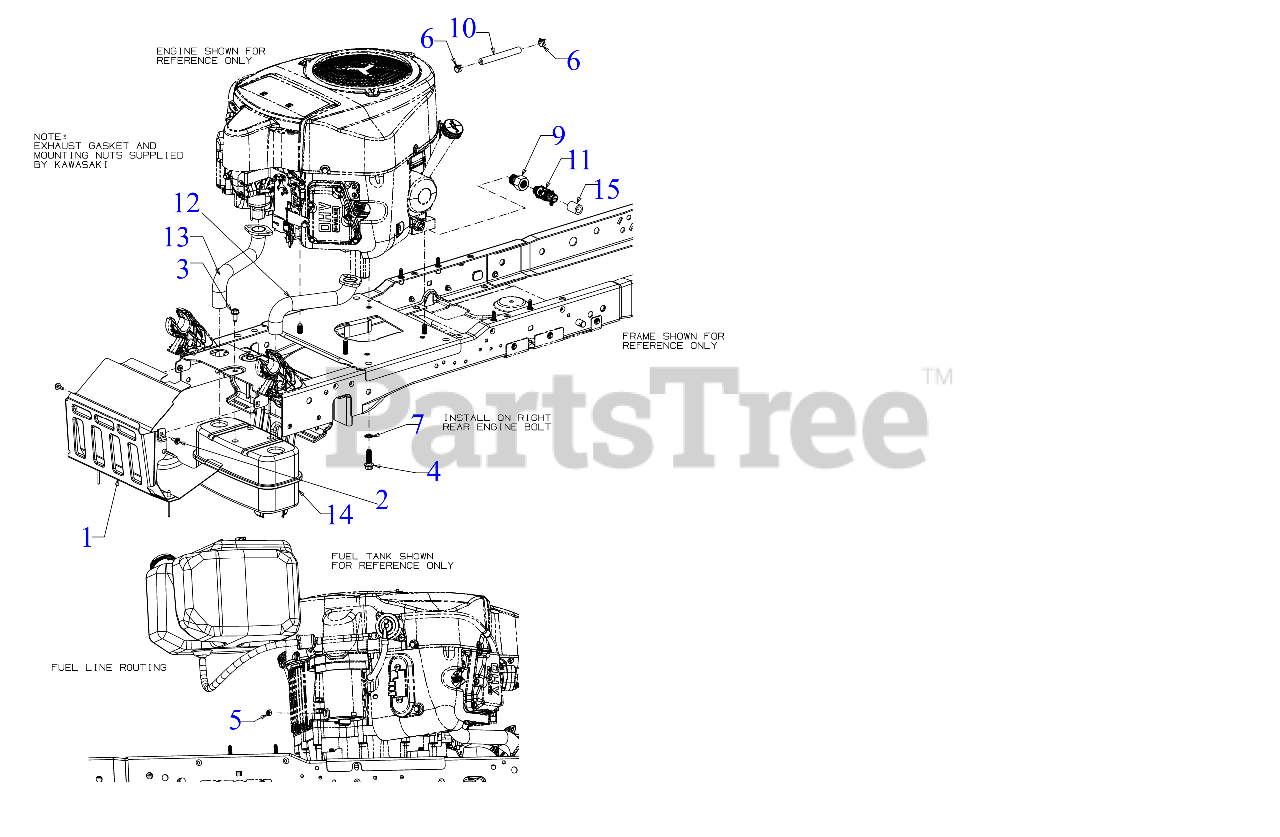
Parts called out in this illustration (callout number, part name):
1	MUFFLER SHIELD ASSEMBLY
2	SCREW M6-1 x .625
3	SCREW M8-1.25 x .750
4	SCREW 3/8-16 X1.250
5	HEX NUT 1/4-20
6	HOSE CLAMP 1/20
7	LOCK WASHER 3/8
9	OIL DRAIN FITTING
10	FUEL HOSE LOW PERMEATION 13"
11	OIL DRAIN VALVE
12	EXHAUST PIPE (LH) (KAWASAKI)
13	EXHAUST PIPE (RH) (KAWASAKI)
14	EXHAUST MUFFLER TWIN
15	DRAIN HOSE 14''
